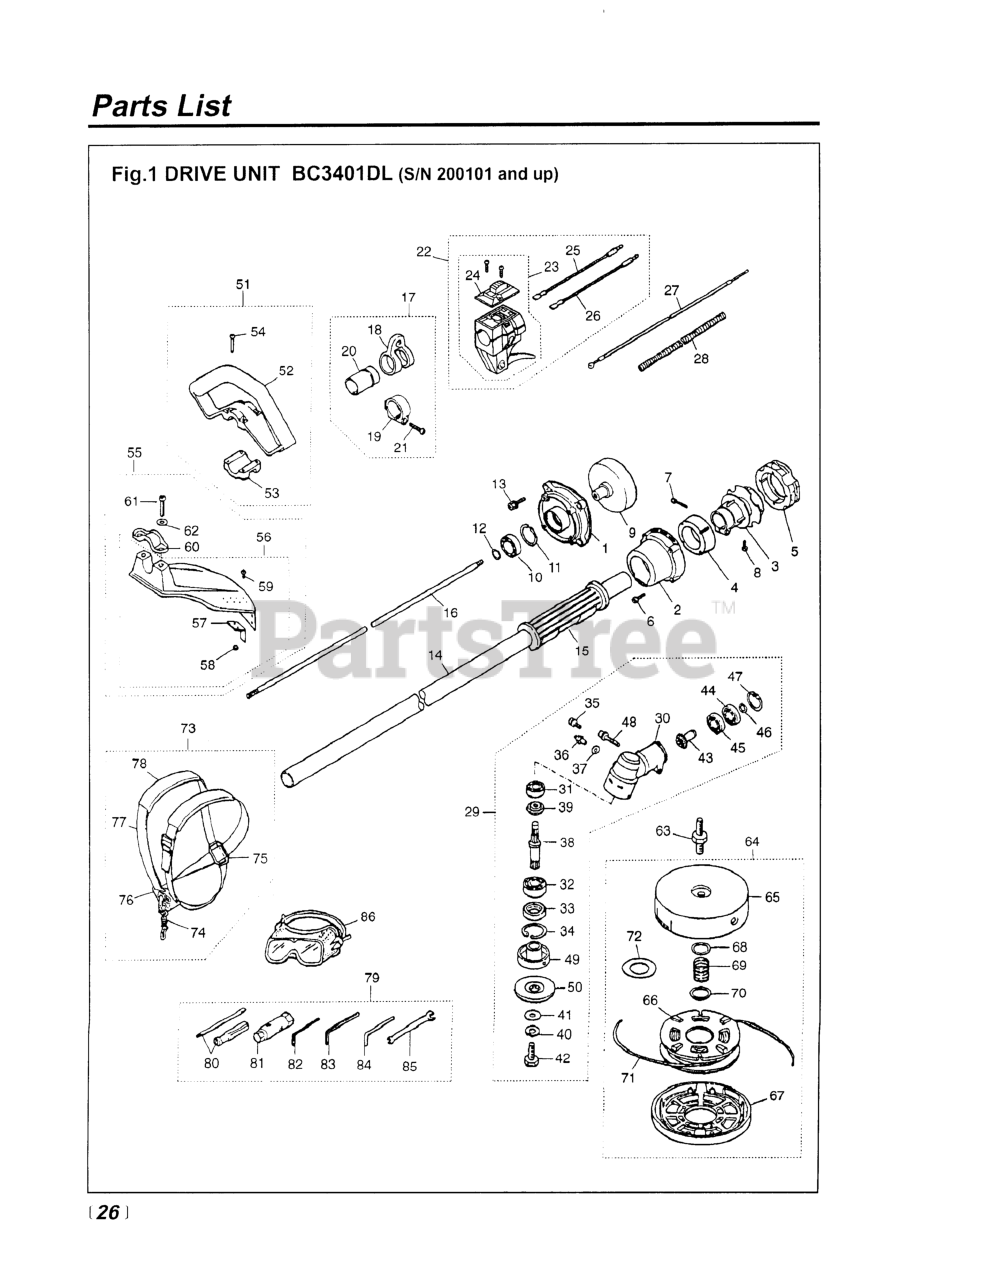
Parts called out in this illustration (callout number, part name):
1	HOUSING
2	CAP
3	JOINT
4	ABSORBER-F
5	ABSORBER-R
6	BOLT, M5 X 30
7	BOLT, M6 x 30
8	BOLT, M5 X 10
10	BEARING
11	RING, SNAP, M35 X 1.5
12	RING, SNAP, M15 X 1.0
13	BOLT, M6 x 20
14	PIPE COMP.
15	GRIP (RPLS 3577-32140 & 3220-
16	SHAFT, DRIVE (REPLACES -12210)
17	HANGER ASSEMBLY
18	HANGER
19	CLAMP
21	SCREW, M5 x 25
22	LEVER COMP. (USE 848-8R2-0351)
25	CORD (A), BLACK
26	CORD (B), RED
27	CABLE COMP (RPLS 1633-83100)
28	TUBE
29	GEAR CASE ASSY.
30	GEARCASE
31	BEARING (RPLS T3403-13510)
33	SEAL, OIL
34	RING, SNAP, M32 x 1.2
35	BOLT, M5 X 10
36	FITTING, GREASE
37	WASHER, M6 X .8
38	SHAFT
39	GEAR, BEVEL
40	WASHER (RPLS 3180-13270)
41	WASHER, M8 x 2.3 (RPLS -20823)
42	BOLT, LH
43	PINION
45	BEARING (RPLS T3403-13510)
46	RING, SNAP
47	RING, SNAP, M26 X 1.2
48	BOLT, M6 x 1.35
49	HOLDER (A)
50	HOLDER (B)
51	HANDLE ASSEMBLY
52	HANDLE
53	CLAMP
54	SCREW, M5 x 35
55	GUARD ASSY (RPLS -24001)
56	GUARD COMP.
57	BLADE
58	NUT
59	SCREW, M5 x 12
60	CLAMP
61	BOLT, M6 x 1.30
62	WASHER, M6 X 15
63	SHAFT (RPLS 3274-99120)
64	6
65	CASE (RPLS. -99111)
66	CORD HOLDER (RPLS. -99140)
67	COVER
68	PLATE, LARGE
69	SPRING (RPLS -99161)
70	PLATE, SMALL
71	CORD
72	SPACER
73	HARNESS ASSY (RPLS -95200)
74	HOOK, HARNESS (RPLS -17210)
76	HANGER COMP.
77	BAND (NOT SOLD SEPARATELY)
78	PROTECTOR
79	TOOL SET
80	SCREWDRIVER
82	WRENCH (TOOL)
83	WRENCH (TOOL)
84	BAR
85	SPANNER, 8 X 10 (RPLS 2540- )
